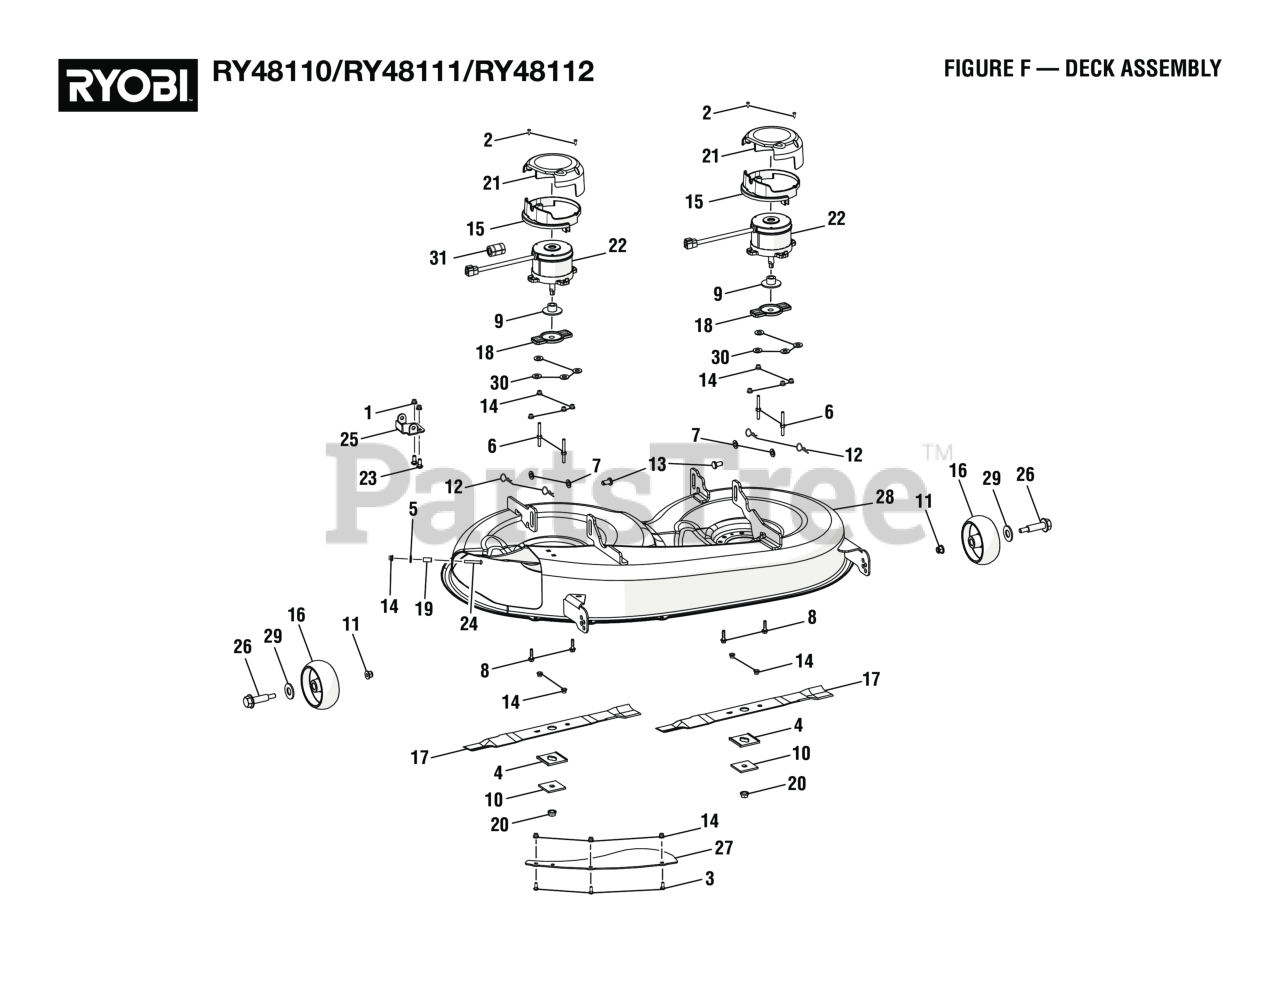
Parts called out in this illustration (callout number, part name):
1	Flange Nut (M8) (For Drive Motor Controller V)
2	Screw (ST4.2 x 13 mm)
3	Carriage Bolt (M6 x 16 mm)
4	Blade Spacer
5	Washer (OD18 x ID6.4 x 1.6t)
6	Threaded Stud (M6 x 35 mm)
7	Washer (OD20 x ID10.5 x 2t)
8	Flange Bolt (M6 x 25 mm, Hex Hd.)
9	Motor Axle Bushing
10	Metal Blade Retainer
11	Lock Nut (M10 x 1.5 mm)
12	Cotter Pin (10 mm)
13	Lifting Plate Pin
14	Flange Lock Nut (M6 x 1.00)
15	Motor Cover
16	Front Deck Roller Wheel (124.5 Dia.)
17	Mulching Blade
18	Blade Holder
19	Deck Bagger Chute Mounting Shaft
20	Flange Lock Nut (M10 x 1.25)
21	Motor Cover Cap
22	Deck Motor
23	Carriage Bolt (M8 x 20 mm)
24	Screw (M6 x 40, Soc Hd.)
25	Mounting Mulch Door Bracket
26	Shoulder Bolt (M10 x 70 mm)
27	Butterfly Bracket
28	Mower Deck w/Brackets
29	Spring Washer (OD20.5 x ID17 x 0.3t)
30	Washer (OD18 x ID6.4 x 3t)
31	Magnetism Ring
